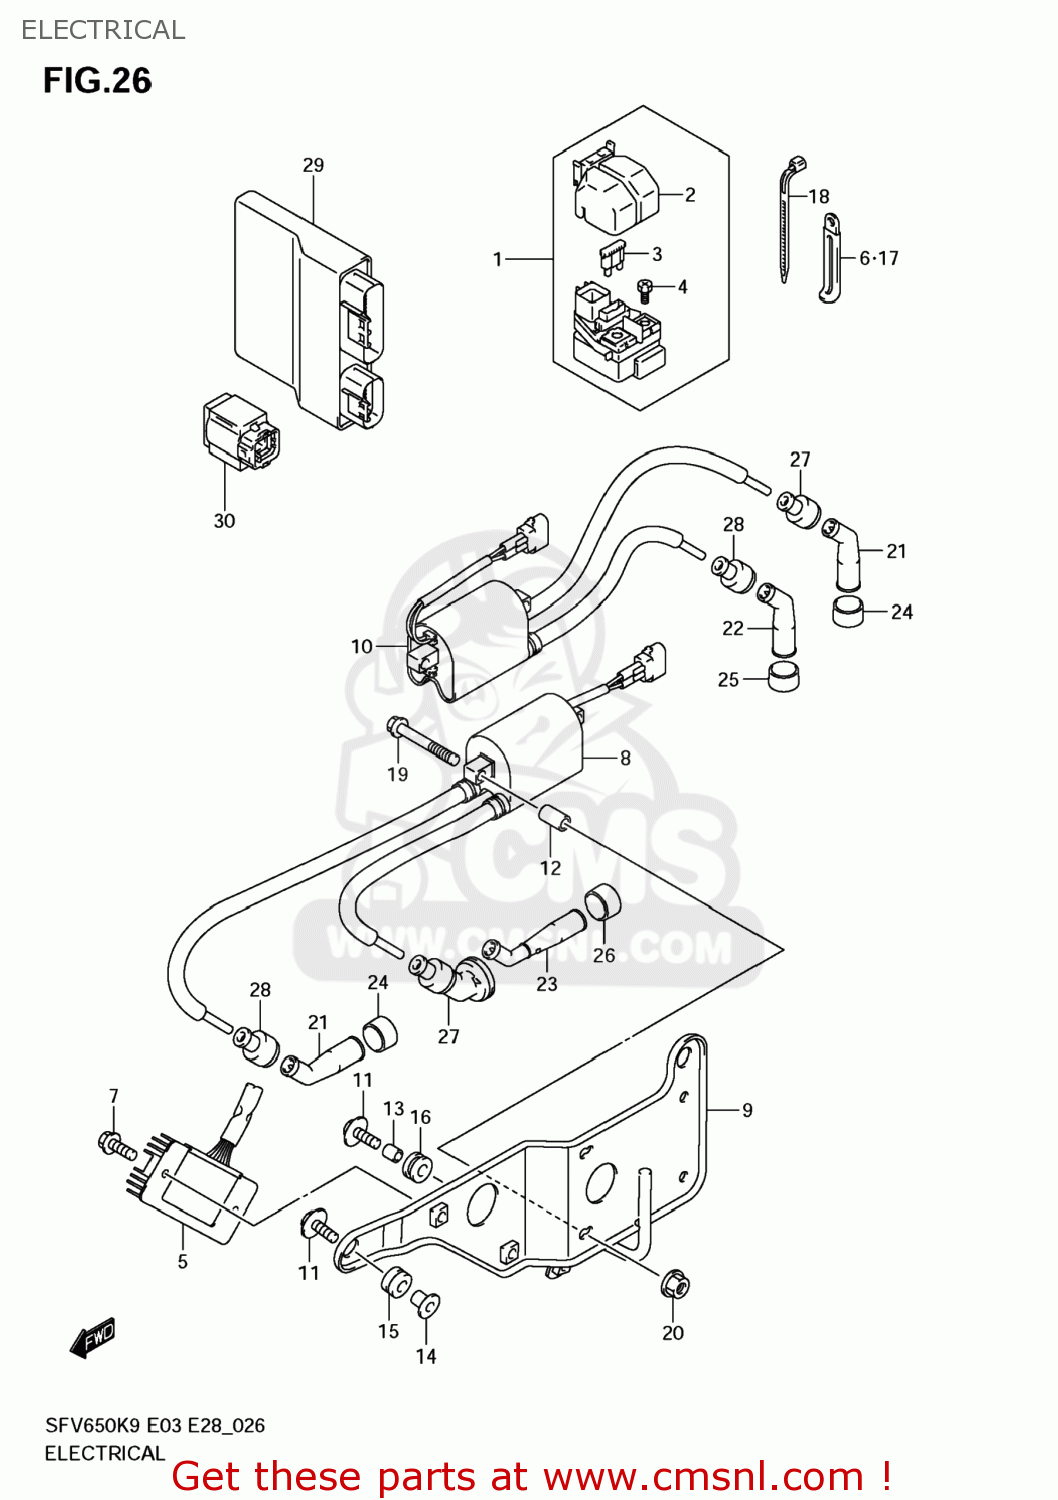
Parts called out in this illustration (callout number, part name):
1	RELAY ASSY,STARTING MOTOR
2	COVER
3	FUSE(30A)
4	SCREW(6X8)
5	RECTIFIER ASSY
6	CLAMP(L:45)
7	SCREW
8	COIL ASSY,IGNITION FR
9	BRACKET,IGN CO
10	COIL ASSY,IGNITION RR
11	BOLT(6X20)
12	SPACER(6.4X10X18)
13	SPACER(6.5X9X9)
14	SPACER(6.2X8.4X10.9)
15	CUSHION
16	CUSHION
17	CLAMP(L:80)
18	CLAMP(L:165)
19	BOLT
20	NUT
21	CAP ASSY,SPARK PLUG
22	CAP ASSY,SPARK PLUG
23	CAP ASSY,SPARK PLUG
24	SEAL,SPARK PLUG
25	SEAL,SPARK PLUG
26	SEAL,SPARK PLUG
27	SEAL,HIGH TENSION CORD CTR
28	SEAL,HIGH TENSION CORD
29	CONTROL UNIT,FI
30	SENSOR ASSY,FUEL CUT
